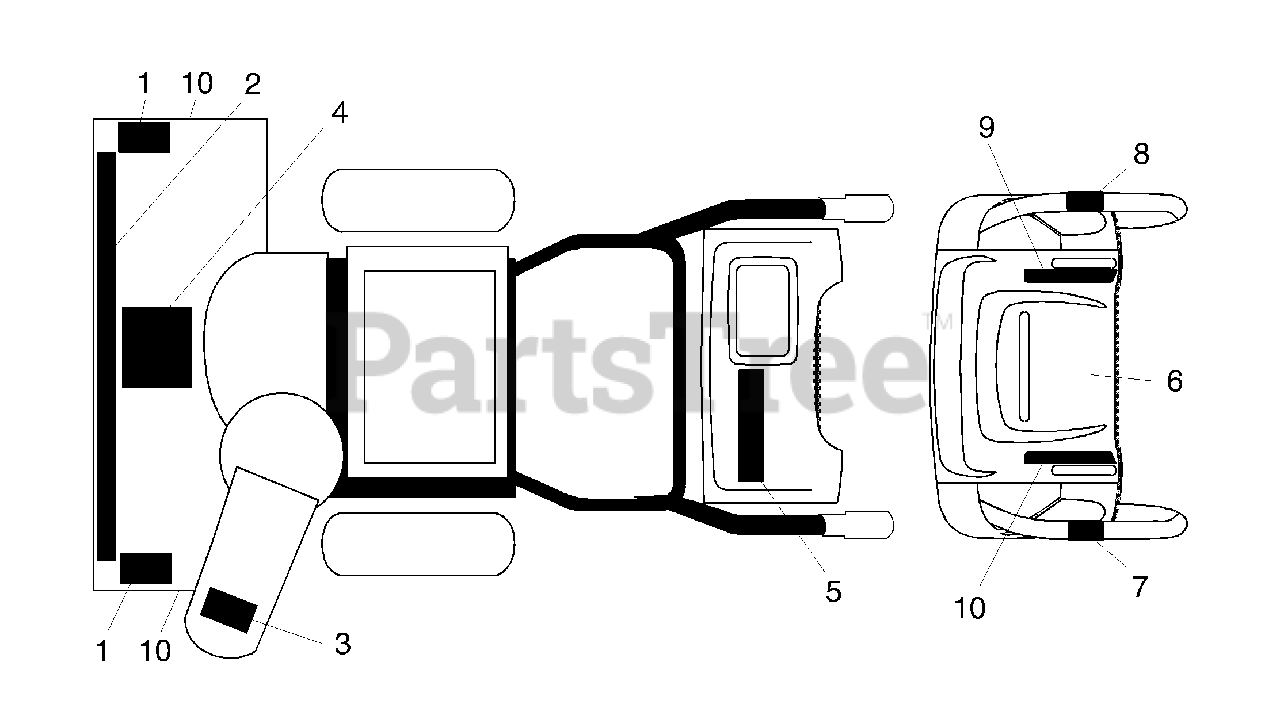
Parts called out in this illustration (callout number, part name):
1	Decal, Danger
2	Decal, Husqvarna
3	Decal, Danger, Deflector
4	Decal, Danger
5	Decal, Husqvarna, 1130STE
6	Decal, Instruction
7	Decal, Traction Lever
8	Decal, Auger Lever
9	Decal, Speed Control
10	Decal, Remote Deflector
10	Decal, Husqvarna
11	Decal, LH Trigger
12	Decal, RH Trigger
